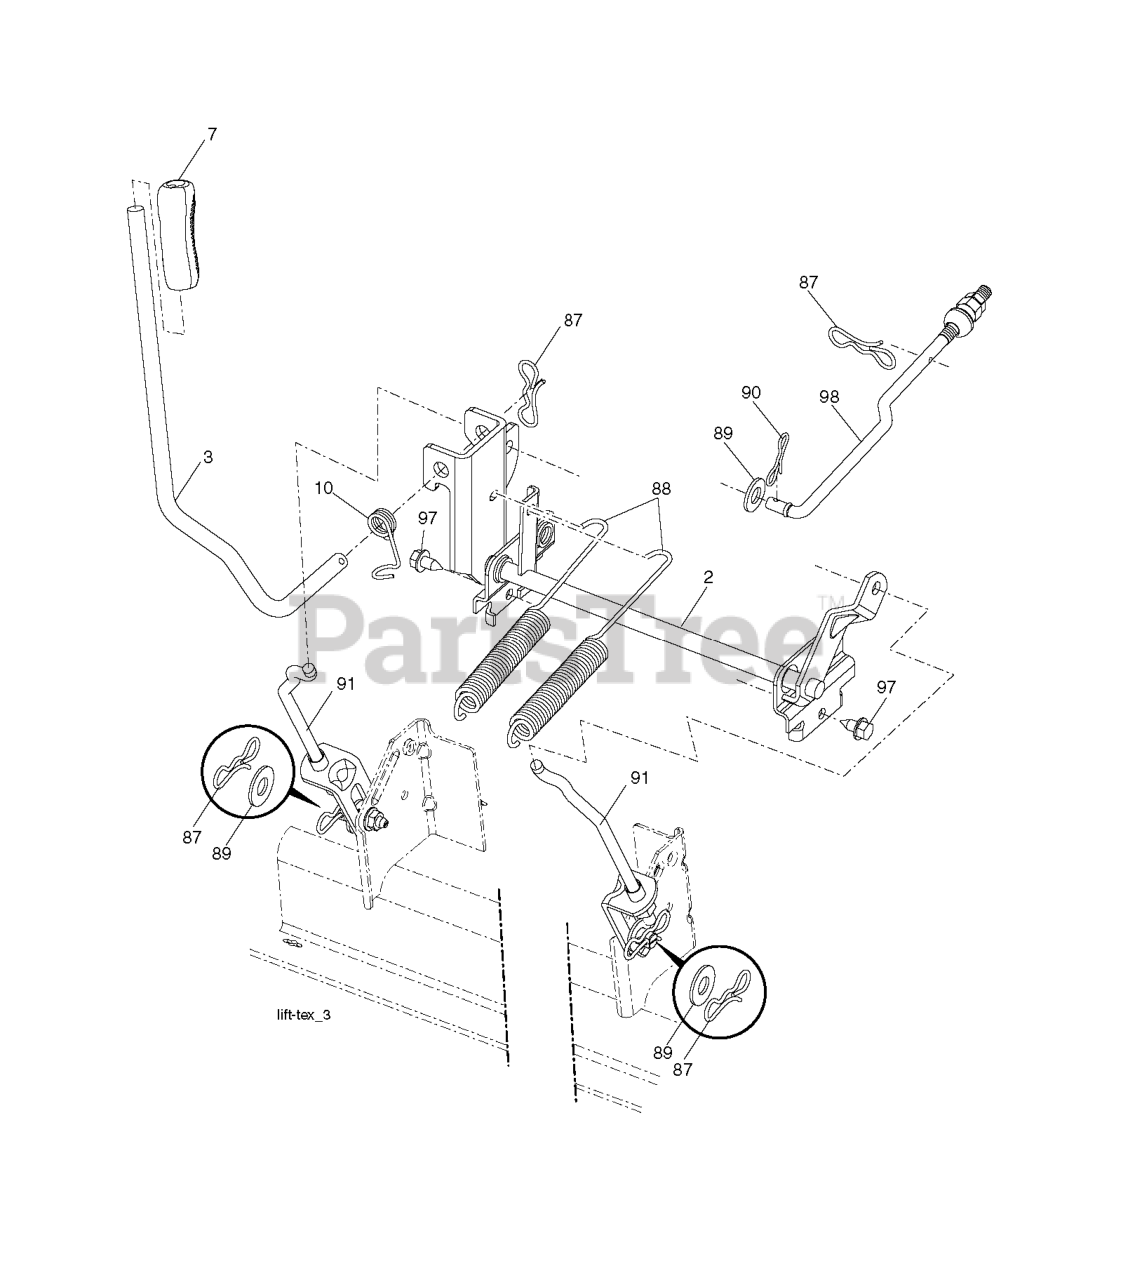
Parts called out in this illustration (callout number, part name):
2	SHAFT.ASM.LIFT.CROSS.H
3	LEVER.LIFT.HANDLE.GT
7	GRIP.HANDLE.LIFT.PVC.BLACK
10	SPRING.TORSION.LIFT.HANDLE
87	PIN.COTTER.7/16.BOW TI.
88	SPRING.LIFT.ASSIST.GT2
89	WASHER.CLEAR.ZINC
90	PIN.COTTER.5/16.BOW TI
91	LINK.LIFT.ASM.REAR.GT.
97	SCREW 3/8-16X3/4
98	LINK.ASM.SUSP.FRONT.MWR.10.5
